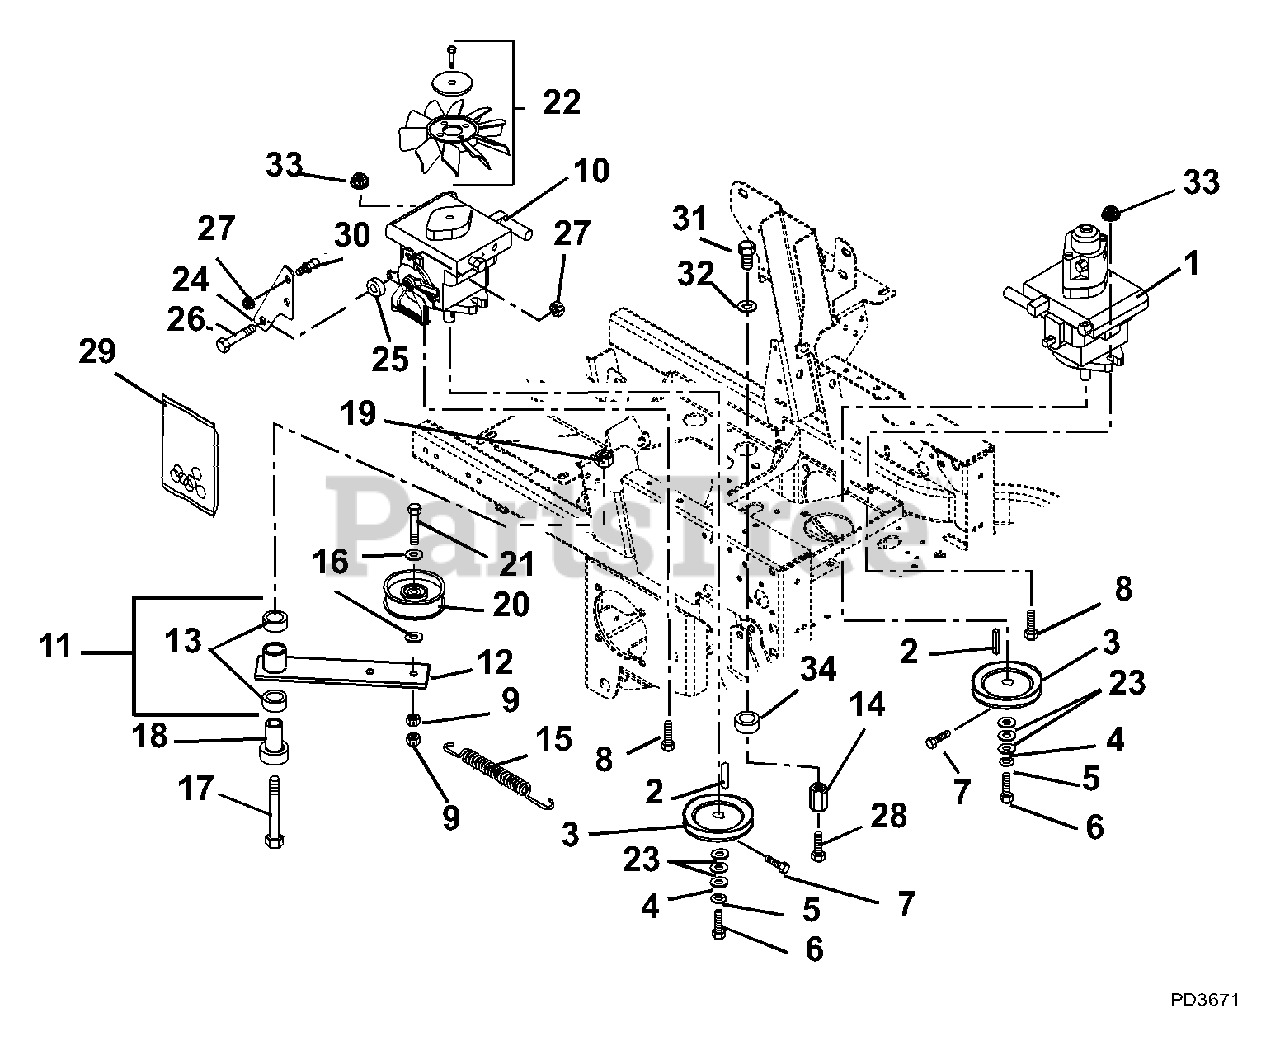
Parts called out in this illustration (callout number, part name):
1	Hydrostat BDP with Auxiliary
1	Pump, Hydraulic BDP-10A Left Hand
1	Pump, Hydraulic PJ-Series 12CC with Fan
2	Key, Straight 5mm x 25mm x 5mm
3	Sheave, .593 x 5.831
3	Sheave, 4.0 x .199
4	Washer, Flat Steel .281 x 1.00 x .063
5	Washer, Locking .25 x .062
6	Bolt, Hex M6 x 1.0 x 12
7	Bolt, Hex .25-20 x .50 Grade 5
8	Bolt-Round Head Square Neck .44-14 x 1.50 Grade 5
9	Nut, Locking Top Flange .38-16
10	Pump, Hydraulic
10	Pump, Hydraulic with Fan
11	Assembly, Idler Arm Guard Drive
12	Weldment, Idler Arm Ground Drive
13	Bearing, 1.00 x 1.12 x .75
14	Nut Coupling .375-16 x 1.75
15	Spring, Tension .120 x .845 x 6.50
16	Washer, Flat Steel .39 x.75 x.125
17	Bolt, Hex .50-13 x 3.50 Grade 5
18	Bearing, Pedestal
19	Nut, Locking Top Flange .50-13
20	Idler-Flat 4.00 x .38
21	Bolt, Hex .38-16 x 2.25 Grade 5
22	Fan, Cooling
23	Washer, Flat Steel .656 x 1.31 x .095
24	Bracket, Return to Neutral/Damper
25	Spacer .344 x 1.00 x .375
26	Bolt, Hex .31-18 x 1.25 Grade 5
27	Nut, Locking Top Flange .31-18
28	Bolt-Hex .38-16 x 1.50 Grade 5
29	Kit, Pump Seal
30	Stud, Ball
31	Bolt-Hex .38-16 x 1.00 Grade 5
32	Washer, Locking .38 x .094
33	Nut-Nyloc Flange .44-14
34	Bushing-Sleeve .377 x .624 x .370
